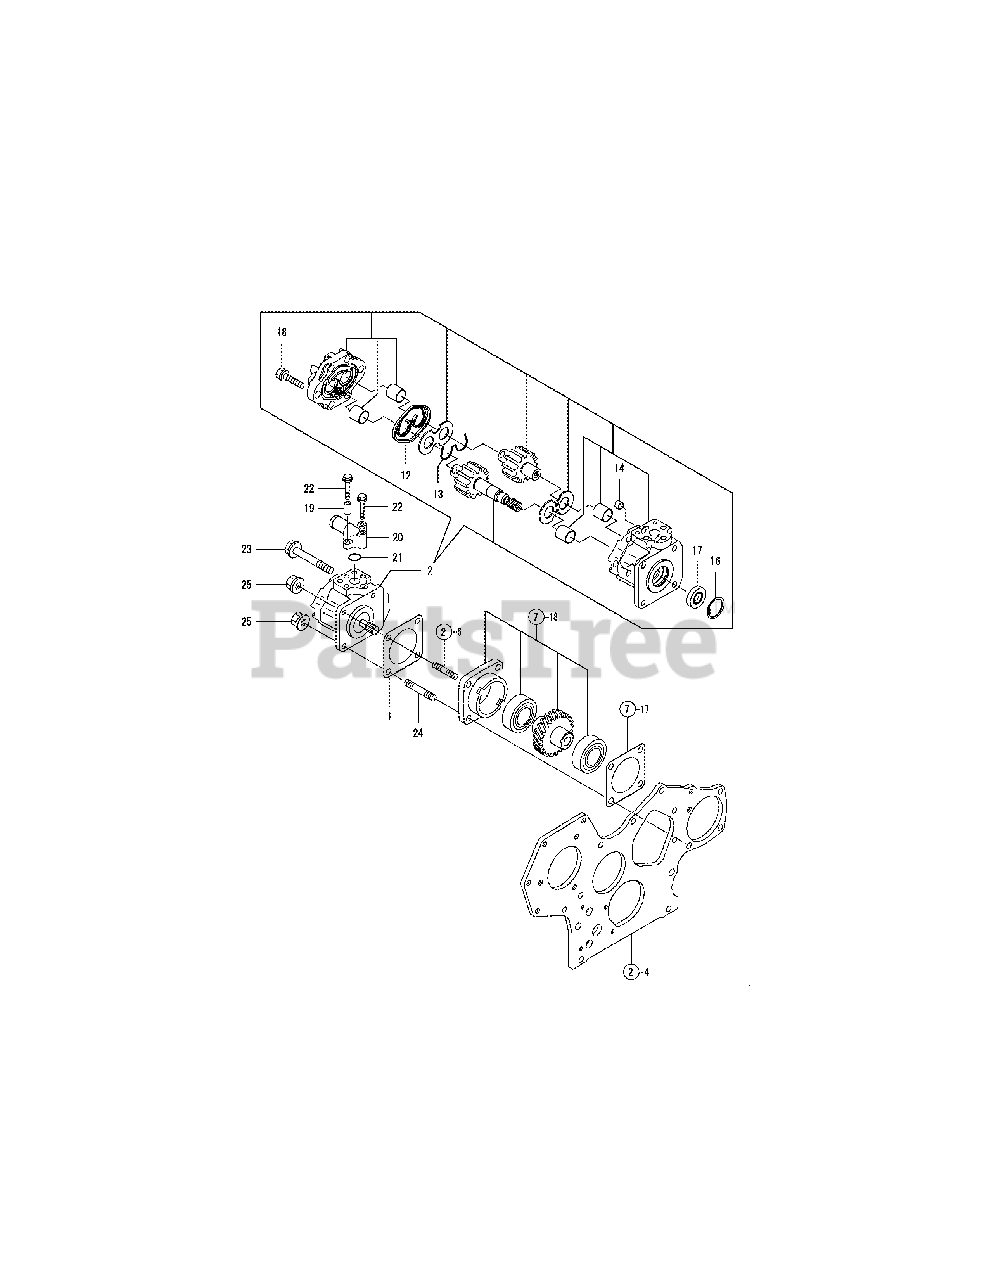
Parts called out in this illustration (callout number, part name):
1	GASKET, HYD. PUMP
2	PUMP, HYDRAULIC
17	SEAL, TC153207
19	SPACER, FLANGE
21	PACKING, P 20.0
24	STUD,BOLT 8 X 40
